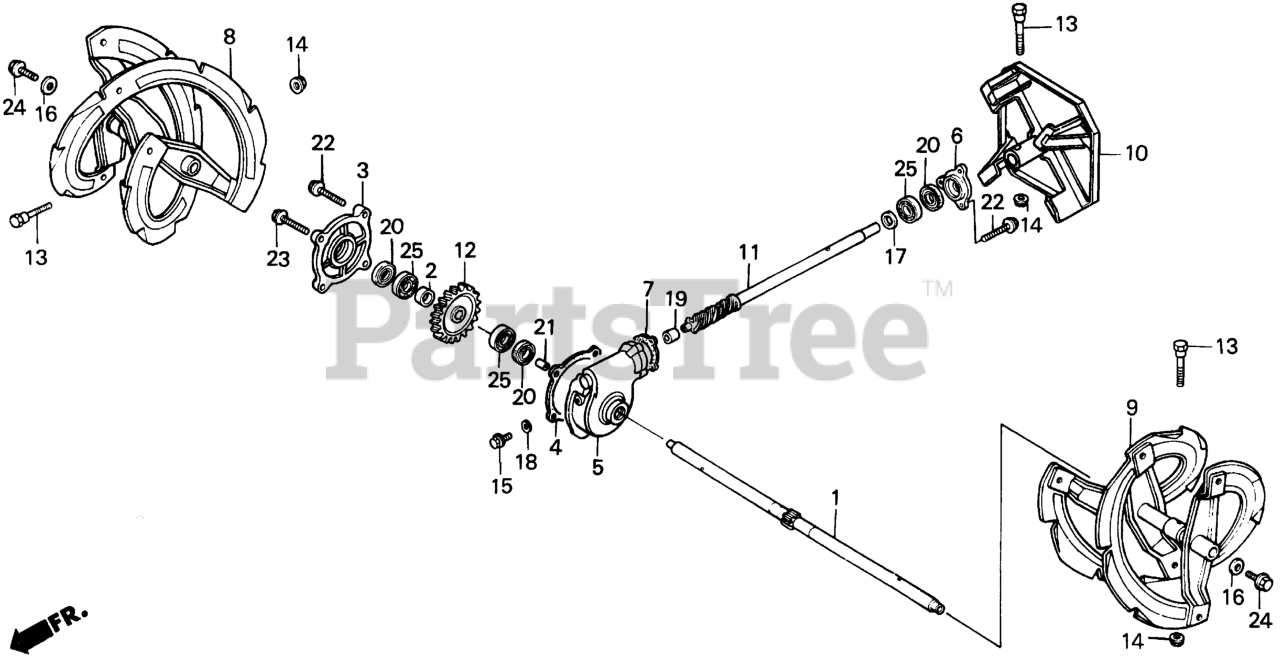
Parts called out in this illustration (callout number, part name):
1	SHAFT, AUGER (NOT AVAILABLE)
2	COLLAR, DISTANCE
3	COVER, AUGER TRANSMISSION (NOT AVAILABLE)
4	GASKET, AUGER TRANSMISSION CASE (NOT AVAILABLE)
5	CASE, L. AUGER TRANSMISSION
6	CAP, AUGER CASE (NOT AVAILABLE)
7	GASKET, AUGER CASE CAP (NOT AVAILABLE)
10	BLOWER (14")
11	GEAR, DRIVE (NOT AVAILABLE)
12	GEAR, DRIVEN (NOT AVAILABLE)
13	BOLT, LOCK
14	NUT, SELF-LOCK (6MM)
16	WASHER (8MM)
17	WASHER, THRUST (27X20X1.0)
19	BEARING, NEEDLE (15MM)
20	OIL SEAL (20X32X7)
21	PIN A, DOWEL (8X14)
22	BOLT, FLANGE (6X20)
23	BOLT, FLANGE (6X28)
24	BOLT, FLANGE (8X16) Use from Engine SN 1000016.
25	BEARING, RADIAL BALL (6004)
